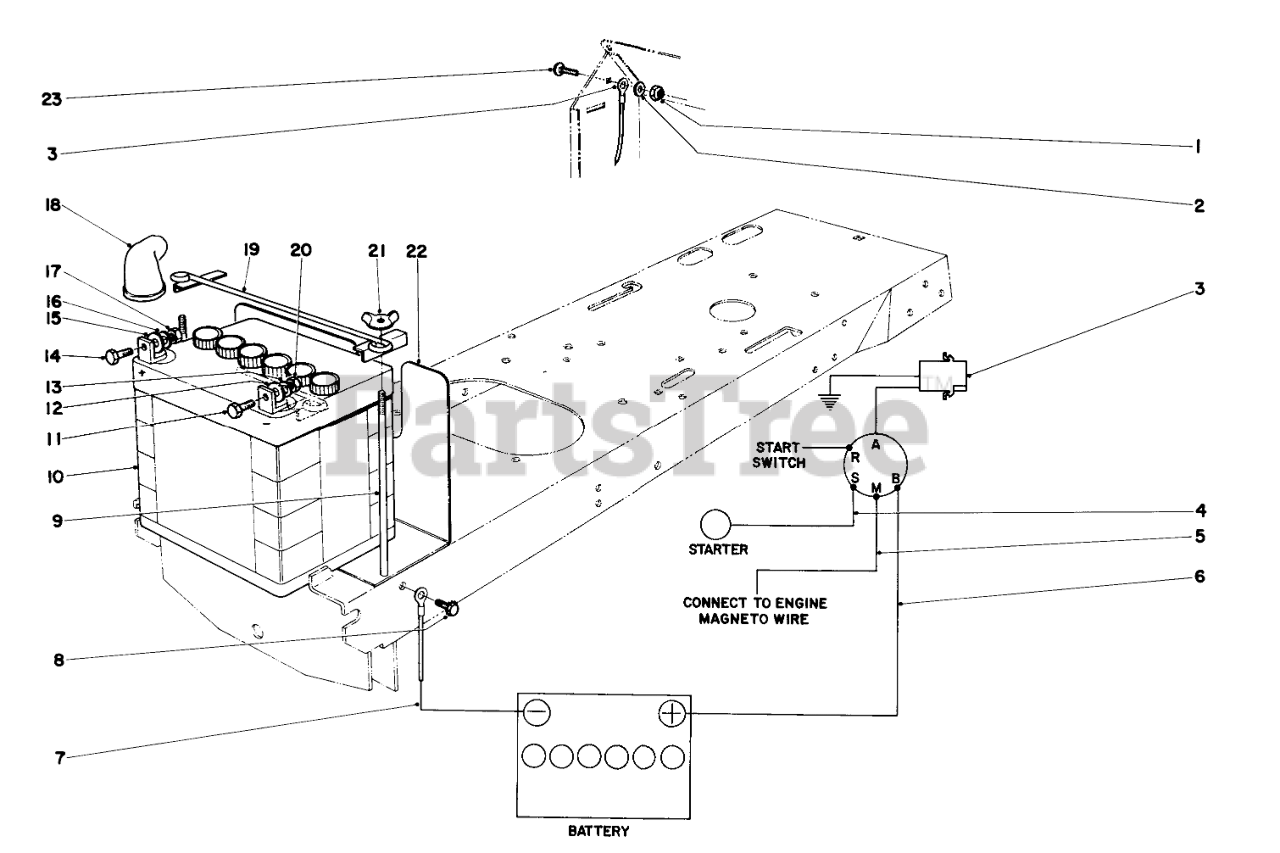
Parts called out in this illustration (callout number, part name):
1	NUT-LOCK, CONE
2	WASHER-FLAT
3	Wire Assembly
4	Wire Assembly
5	Wire Assembly
7	Wire Assembly
8	1/4-20X5/8 THDG SEMS
9	BATTERY BOLT
10	Battery
11	SCREW-HH
12	WASHER-FLAT
13	WASHER-LOCK
14	SCREW-HH
15	WASHER-FLAT
16	WASHER-LOCK/SP
17	NUT-HEX
18	BATTERY BOOT
19	Clamp
20	NUT-HEX
21	WING NUT
22	Heat Shield Battery
23	SCREW-CARR
